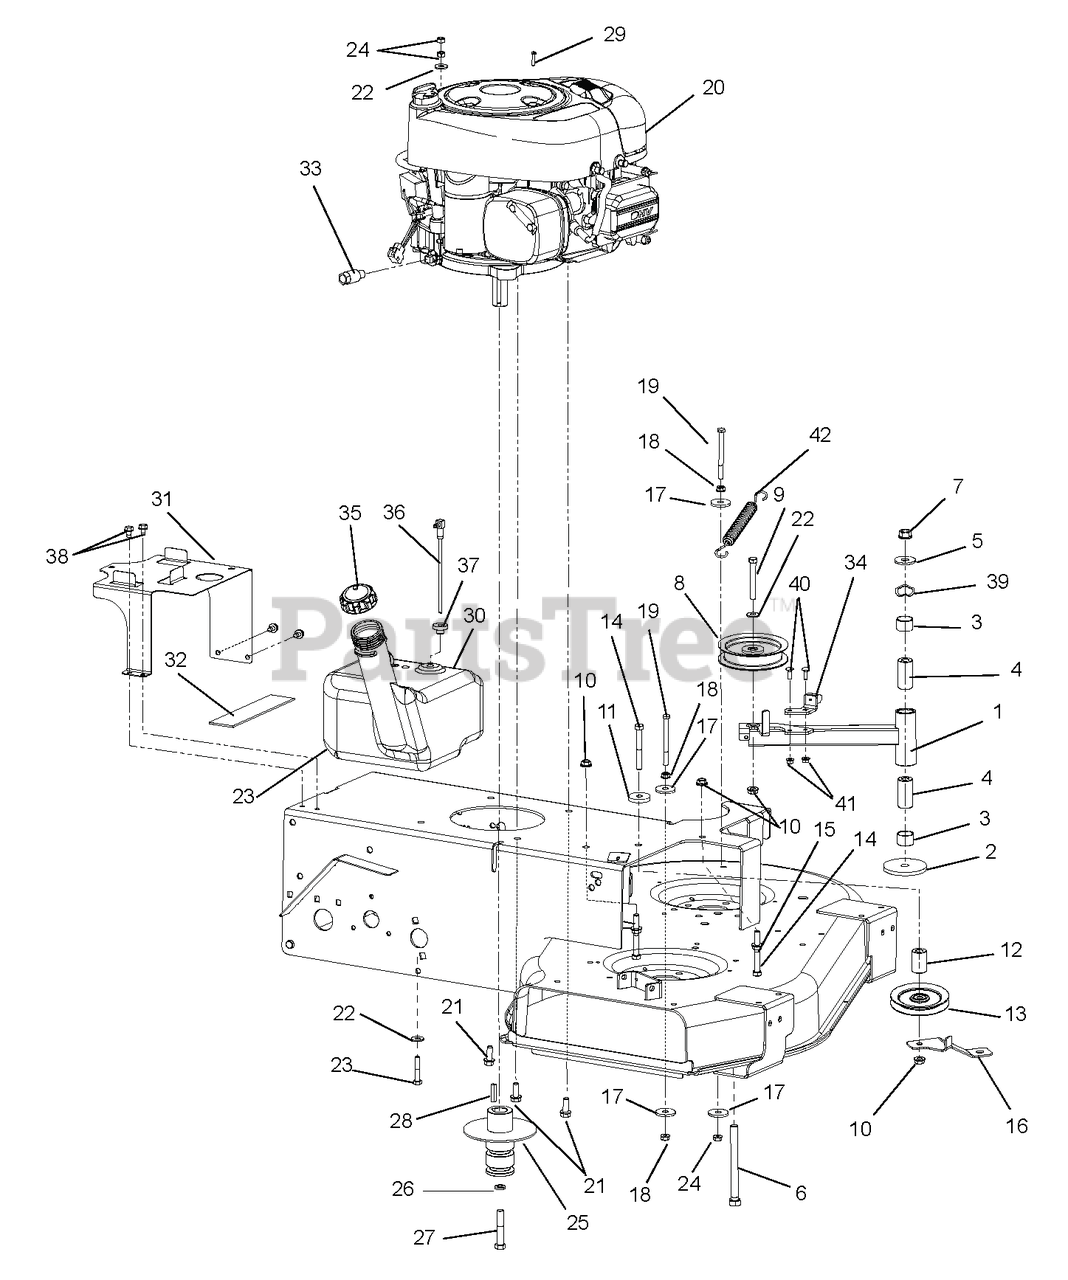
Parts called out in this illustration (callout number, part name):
1	WLDMT, PTO IDLER ARM
2	WASHER, FLAT .531X3.000X.25
3	BRG, 1.00 X 1.12 X .75
4	BSHG, SPCR .502X.997X2.03 PM
5	WSHR-FL-STL.511X1.441X.125 YWZ
6	@BLT-HEX .50-13X5.50 GR5YWZC
7	@NUT-LK-TOP-FLG .50-13 YWZC
8	ASM, IDLER 4"
9	@BLT-HEX .38-16X2.75 GR5 YWZC
10	@NUT-LK-TOP-FLG .38-16 YWZC
11	WSHR,FLT STL.406X1.50X.245YWZC
12	SPACER, .437X1.0X1.23
13	SHV, .38"ID X 4.00"OD V-IDLER
14	@BLT-HEX .38-16X3.00 GR5 YWZC
15	@NUT-SPNLK-FLG .375-16 YWZC
16	BRKT-IDLER BRACE
17	WSHR-FL-STL .406X1.375X.135 YZ
18	@NUT-SPNLK-FLG .312-18 YWZC
19	@BLT-HEX .31-18X3.50 GR5 YWZC
20	ENGINE, B&S 14.5 POWERBUILT
21	@SCR-TAP .38-16X1.00 HWH TR YZ
22	@WSHR-FL-STL.38X.875X.083 YWZC
23	@BLT-HEX .31-18X1.75 GR5 YWZC
24	@NUT-LK-CTR .31-18 YWZC
25	PULLEY, PRO-GROUND DRIVE
26	@WSHR-LK .44X.109 REG YWZC
27	BLT-HEX .44-20X2.50 G5 YZ EP80
28	KEY-SQ .25 X 1.25 X .25 SAE
30	TANK, FUEL (BLACK)
31	BRKT, GAS TANK MOUNT
32	PAD, GAS TANK
33	DRAIN, OIL
34	ASSY, WAW WEDGE BRAKE
34	BRAKE PAD ASSY WAW
35	FUEL CAP
36	ASSY-PICKUP, FUEL 6.5L
38	@SCR-TAP .31-18X.50 HWH TR YWZ
39	WASHER - WAVE 1.09X1.37X.016
40	@BLT-RDHDSQNK .25-20X.75 G5YZ
41	@NUT-LK-TOP-FLG .25-20 YWZC
42	DECAL, ARIENS HERITAGE-LARGE
